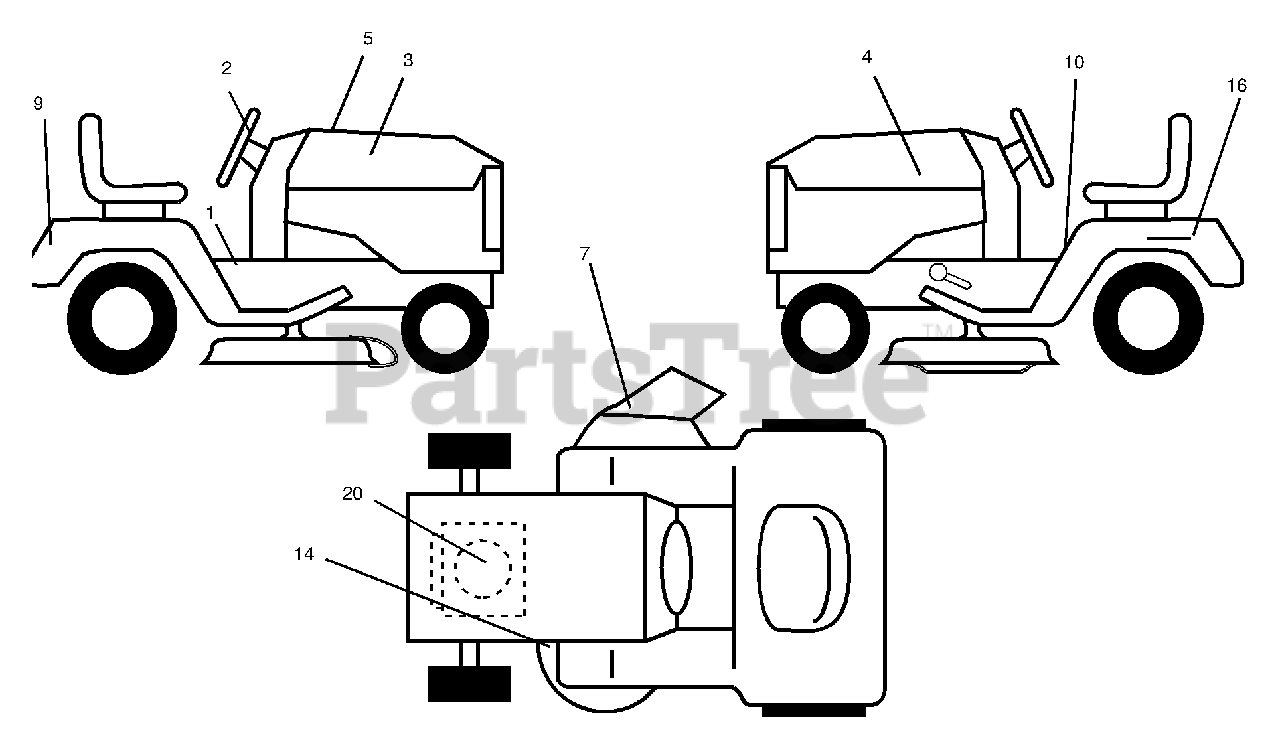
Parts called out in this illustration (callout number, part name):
1	Decal Instruction Operat English/French
2	Decal Ins Strg Whl Statesman
2	Decal Ins Strg Whl Agway
3	Decal Hood RH Statesman
3	Decal Hood RH Agway
4	Decal Hood LH Statesman
4	Decal Hood LH Agway
5	Decal Final Replacement
7	Decal Deck "B" 42"
9	Decal Fender Statesman
9	Decal Fender Agway
10	Decal Danger English
14	Decal V-belt Schematic 42"
16	Decal Battery Danger/Poison
20	Decal HP Engine
